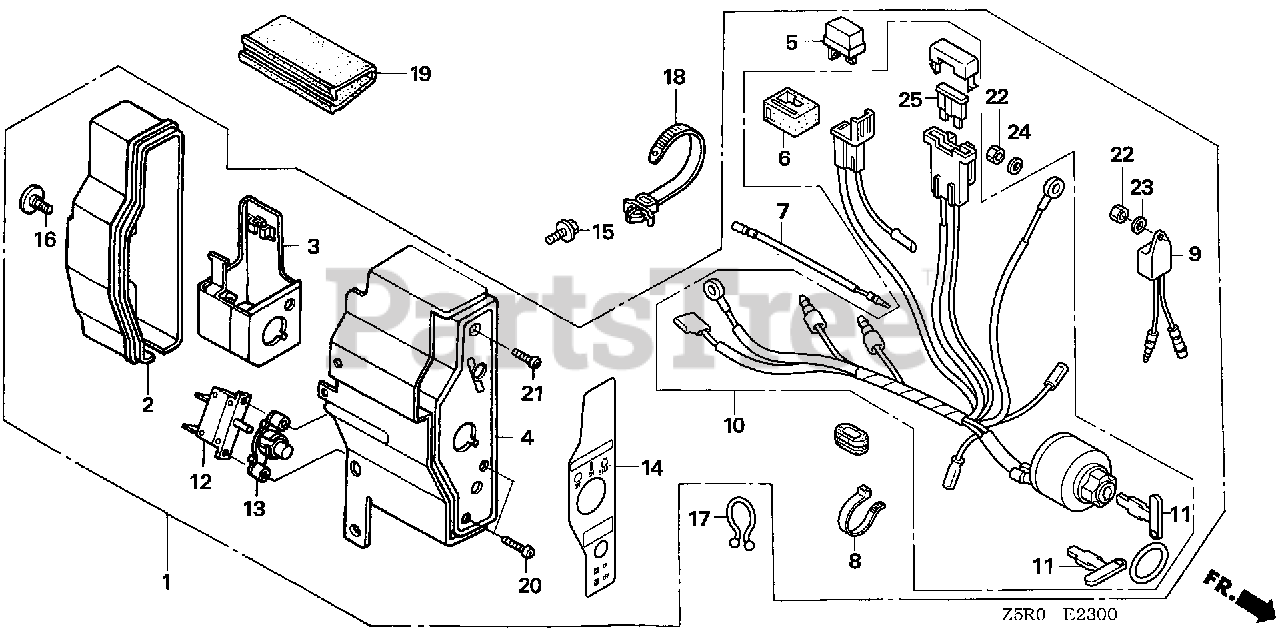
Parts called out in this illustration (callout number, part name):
1	BOX ASSY., CONTROL *NH105* (EXP-ALERT) (MAT BLACK)
1	BOX ASSY., CONTROL *R280* (EXP-ALERT) (POWER RED)
2	CASE, CONTROL
3	BRACKET, CASE MOUNTING
4	PANEL, CONTROL *NH105* (MAT BLACK)
4	PANEL, CONTROL *R280* (POWER RED)
5	RECTIFIER ASSY., SILICON (SHINDENGEN)
6	SUSPENSION, CONNECTOR
7	SUB-WIRE HARNESS
8	BAND
9	ALERT UNIT, OIL
10	SWITCH ASSY., COMBINATION
11	KEY
12	PROTECTOR, CIRCUIT (1.0A)
13	LENS ASSY., PROTECTOR
14	MARK, CONTROL BOX (EXTERNAL)
15	BOLT, FLANGE (6X12) (CT200)
16	SCREW, SPECIAL (6X12)
17	CLIP, PURSE LOCK
18	STRAP, CABLE (118MM) *NH1L* (Honda Code 1170653). (BLACK)
19	TUBE, FASTENER (30)
20	SCREW, PAN (3X12)
21	SCREW, PAN (4X12)
22	NUT, HEX. (4MM)
23	WASHER, PLAIN (4MM)
24	WASHER, SPRING (4MM)
25	FUSE, BLADE (5A)
